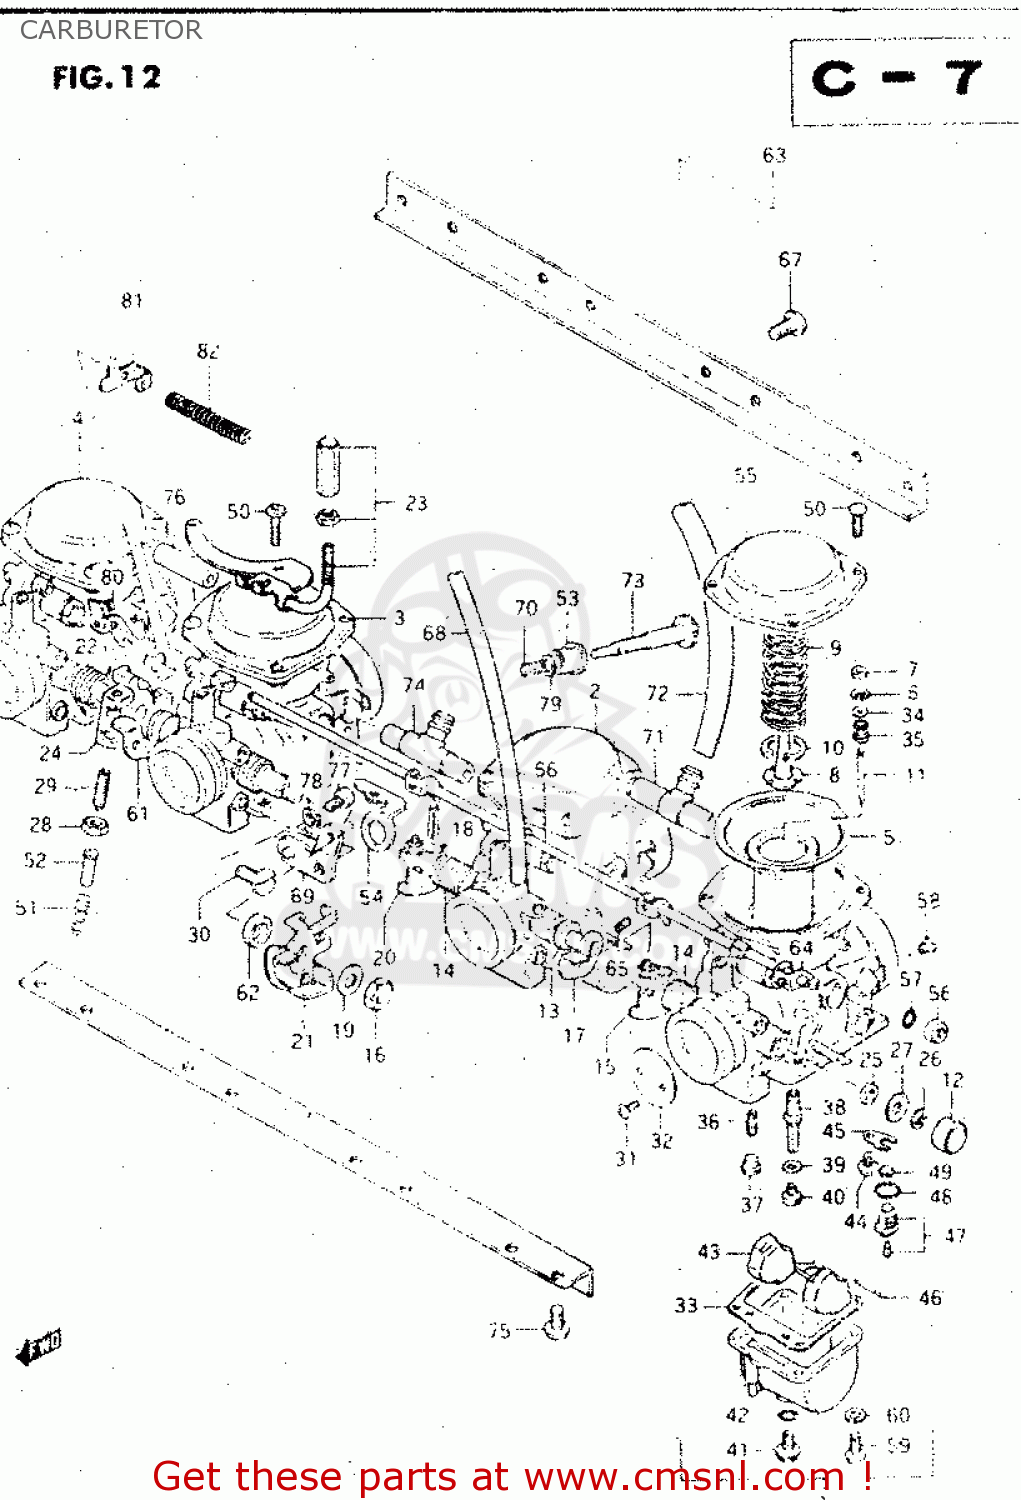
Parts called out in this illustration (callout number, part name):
1	CARBURETOR ASSY, LH
2	CARBURETOR ASSY, ML
3	CARBURETOR ASSY, MR
4	CARBURETOR ASSY, RH
5	DIAPHRAGM ASSEMBLY
6	CLIP,NEEDLE
7	RING
8	HOLDER,GUIDE
9	SPRING
10	E RING
11	NEEDLE, JET (5F42-3)
12	CAP
13	GASKET,THROTTLE SHAFT (NAS)
14	SPRING,THROTTLE SHAFT
15	SHAFT,THROTTLE
16	NUT 8MM
17	SHAFT,THROTTLE
18	PIN,THROTTLE SHAFT
19	WASHER
20	LEVER,THROTTLE SHAFT
21	LEVER ASSEMBLY,THROTTLE
22	SPRING,THROTTLE SHAFT
23	BRACKET,THROTTLE CABLE
24	SHAFT,THROTTLE
25	SEAL
26	E RING
27	GASKET,THROTTLE SHAFT (NAS)
28	NUT
29	SCREW
30	SCREW
31	SCREW
32	VALVE,THROTTLE (BUTTERFLY)
33	GASKET,FLOAT CHAMBER (NAS)
34	WASHER
35	SPRING
36	JET
37	PLUG,NEEDLE JET
38	JET, NEEDLE (X-6)
39	WASHER,NEEDLE NOZZLE
40	JET,MAIN(97.5)
41	PLUG,DRAIN
42	GASKET (NAS)
43	FLOAT
44	SCREW 4X6
45	PLATE,NEEDLE VALVE FITING
46	PIN,FLOAT
47	VALVE ASSEMBLY,NEEDLE
48	O-RING,NEEDLE VALVE
49	FILTER
50	SCREW
51	SPRING,THROTTLE SCREW
52	PIN,THROTTLE LEVER
53	BUSH
54	BRACKET,THROTTLE ADJUST
55	COVER,DIAPHRAGM
56	CAP,STARTER VALVE
57	O RING
58	JET,AIR
59	SCREW
60	LOCK WASHER
61	SHAFT,THROTTLE
62	WASHER
63	CARBURETOR ASSEMBLY
64	LEVER
65	SCREW
66	SHAFT,STARTER
67	SCREW
68	HOSE
69	BRACKET,THROTTLE ADJUST
70	SPRING
71	NIPPLE
72	HOSE
73	SCREW
74	NIPPLE,CARBURETOR
75	SCREW 6X12
76	NIPPLE
77	SCREW
78	LOCK WASHER
79	WASHER
80	LEVER,CHOKE CABLE
81	PLATE,CHOKE CABLE
82	SPRING,CHOKE CABLE
